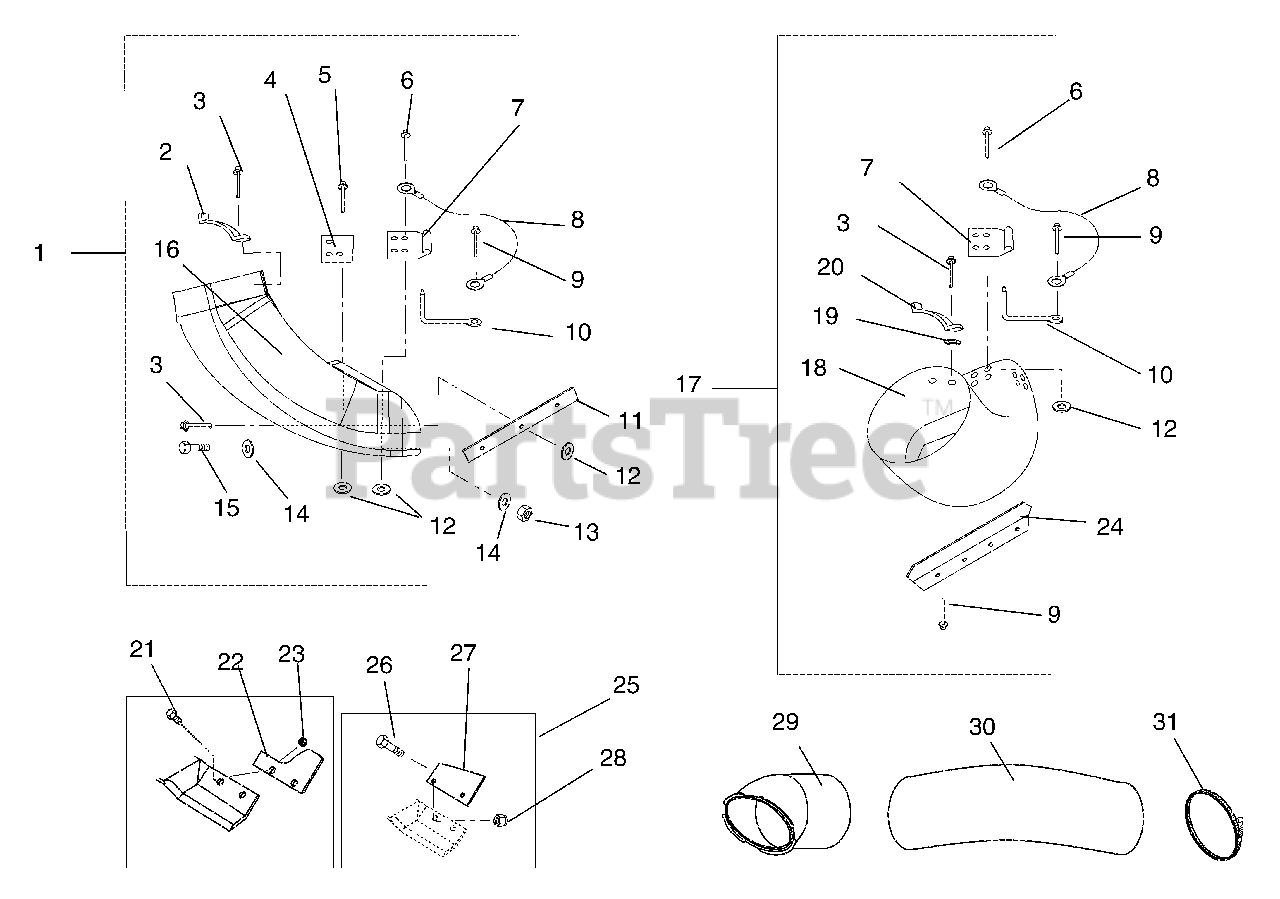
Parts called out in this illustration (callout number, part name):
1	BOOT ASSY, 28/32" BAGGER
2	TUBE RETAINER
3	RVT-POP.187X.527 DOME ST
4	BOOT SUPPORT
5	RVT-POP.187X.277 DOME ST
6	RVT-POP .187X.402 DOME ST
7	BOOT BRACKET
8	LANYARD
9	RVT-TBLR .187X.375 ST-AL PL
10	PULL PIN
11	SKIRT, RUBBER
12	@WSHR-FL-STL.219X.50X.049 YWZC
13	@NUT-LK-NYL .250-20 YWZC
14	@WSHR-FL-STL.281X.62X.065 YWZC
15	@BLT-HEX .25-20X.75 GR5 YWZC
16	28"/32" BOOT ASSY
17	MOWER BOOT ASSY- 40"
18	PAN BOOT ASSEMBLY
19	@WSHR-FL-STL.219X.50X.049 YWZC
20	TUBE RETAINER CLIP
21	BLT-HEX .31-24X.75 GR8 YWZC
23	NUT-CTRLK .31-24 YWZC
24	EXTENSION-CHUTE
25	SERVICE VANE PACKAGE
26	BLT-HEX .31-24X.75 GR8 YWZC
27	VANE
28	NUT-CTRLK .31-24 YWZC
29	BAGGER BOOT - UPPER
30	HOSE 7X38
31	CLAMP, 7" TOOL-LESS HOSE
